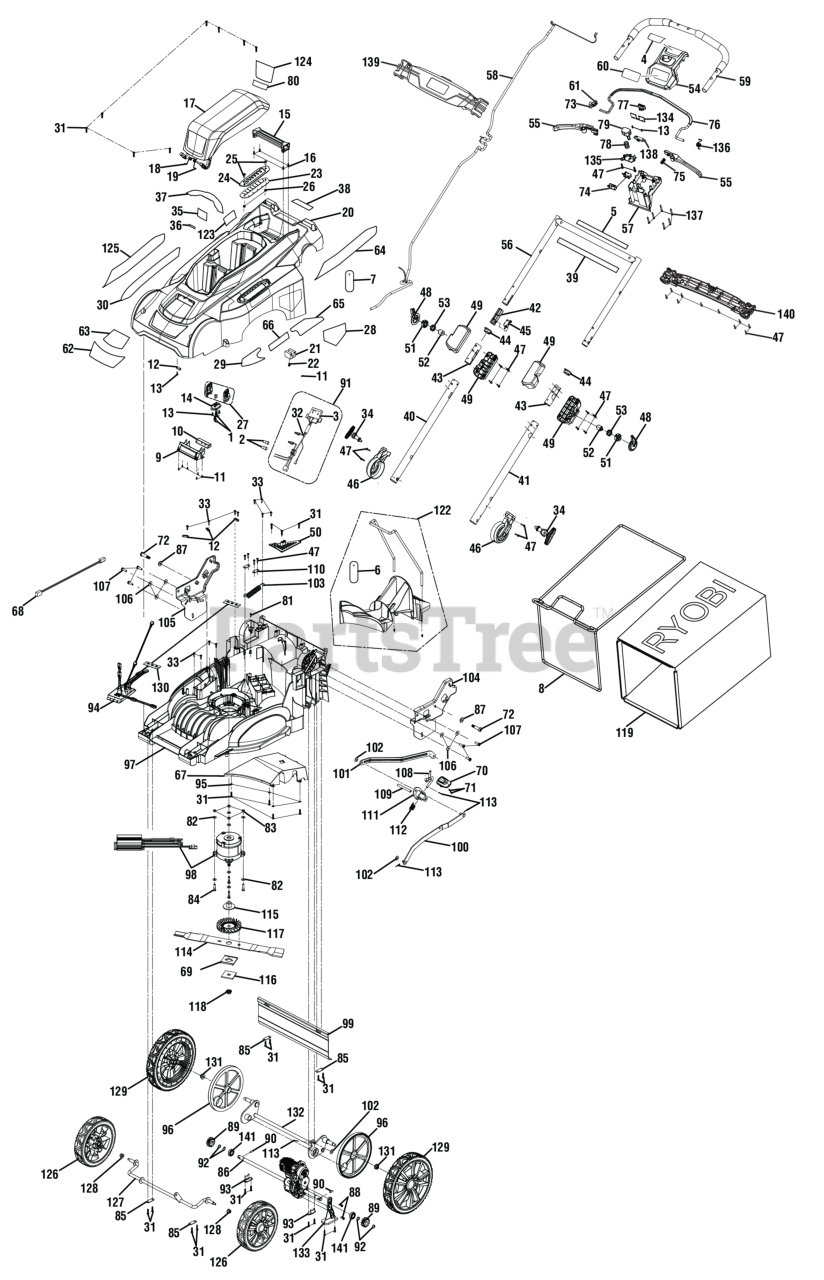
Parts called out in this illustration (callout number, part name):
1	Female Terminal
2	Close-End Connector
3	Battery Hold Assembly
4	Starting Instructions Label
5	Handles Fully Extended Label
6	Mulch Plug Hangtag
7	Start Key Hangtag
8	FRAME, 20 INCH GRASS BAG, BLACK
9	LED Cover
10	Light Reflector
11	Screw (M3 x 8 mm, Pan Hd., Pan Hd)
12	Wire Press Plate
13	Screw (M4.2 x 12 mm, T20 Torx Pan Hd.)
14	Key Holder
15	Carry Handle
16	Screw (M4 x 10 mm, T20 Torx Pan Hd.)
17	Battery Cover (Inc. Key Nos. 80 & 124)
18	Battery Door Right Torsion Spring
19	Battery Door Left Torsion Spring
20	TOP COVER W/ LABELS
21	SENSOR SWITCH FOR GRASS BAG
22	Screw w/Washer (M4 x 10 mm, T20 Torx Button Hd.)
23	Shifter Boot
24	Height Adjustment Plate
25	SCREW (M5 x 16 mm SOC. WASHER HD. CAP)
26	Lock Nut (M5 x 0.8 mm)
27	START KEY W/ HANG TAG
28	Danger Label (No Hands/Feet)
29	Front Green Accent Label
30	Side Green Accent Label
31	Screw (M4 x 20 mm, T20 Torx Pan Hd. S.T.)
32	Inner Wire with Terminal
33	Screw (M4 x 16 mm, T20 Torx Pan Hd.).
34	SPRING PIN ADJUSTMENT ASSEMBLY
35	Wet Conditions Warning Label
36	Onboard Battery Storage Label
37	Start Key Warning Label
38	Attachment User Callout Label
39	Handle Logo Label
40	STEEL TUBE,LOW RIGHT HANDLE TUBE
41	STEEL TUBE,LOW LEFT HANDLE TUBE
42	Switch Plug Housing
43	Handle Tube Bushing
44	Handle Tube Bushing (Small)
46	HINGE SHROUD
47	Screw (M4 x 18 mm, T20 Torx Pan Hd.)
48	Side Handle Latch
49	Handle Latch Assembly
50	PLASTIC,COVER FOR TRANSMISSION ASSY\ ABS
51	Disc Holder
52	Side Compression Disc
53	Handle Compression Spring
54	UPPER HANDLE SUPPORT ASSEMBLY W/ LABEL
55	TRIGGER ASSEMBLY
56	UPPER HANDLE TUBE W/ LABEL
57	UPPER HANDLE SUPPORT ASSEMBLY
58	CORD, 5PCS INNER WIRE AND PLUG ASSY
59	Upper Handle Assembly
60	Handles Fully Extended Label
61	Actuator Switch
62	LABEL, FRONT ""BRUSHLESS""
63	Ryobi 40V Lithium Label
64	Brushless Label (Left)
65	Single Point Height Adjustment Label
66	Cut Height Label
68	Inner Wire with Connector Between Transmission & PCBA
71	Screw (M3 x 9 mm, Flat Hd.)
72	Screw (M8 x 33 mm, Hex Hd.)
73	Stop Switch (Momentary Contact)
74	On/Off Switch
75	Compression Spring
76	Bail Handle (Power Lever)
77	Thumb Pad
78	Safety Button Spring
79	Safety Button
80	Main Warning Label (Part 1)
81	Screw (M3 x 12 mm)
82	Washer (ID6.2 x OD15 x 0.08t)
83	Lock Nut (M6)
84	Bolt (M6 x 26 mm, Hex Hd.)
85	Axle Pressure Plate
86	Transmission Assembly
87	Washer (ID8.5 x OD20.5 x 2 mm x 2t)
88	Screw (T20 x 12 mm)
89	Drive Gear
90	Gear Shaft
91	BATTERY HOLDER AND WIRE ASSEMBLY
92	Retaining Ring
93	Mounting Plate
94	DRIVE MOTOR CONTROLLER
95	Washer (ID4.5 x OD10 x 1t)
96	Wheel Cover
98	MOTOR 10035#, CONTROLLER ASSEMBLE,HUAJIE
99	Rear Protective Guard
100	Forward Linkage
101	Rear Lift Rod
102	Washer (ID8.4 x OD18 x 1t)
103	Rentention Spring
104	STAMPING, LEFT HANDLE BRACKET
105	STAMPING, RIGHT HANDLE BRACKET
106	Washer (1/4 in., Type A)
107	Screw (1/4-15 x 3/4 in., T30 Torx Pan Hd.)
108	Lever Arm
109	Axle (Height Adjustment)
110	Pressure Plate (Height Adjustment)
111	Height Adjustment Bracket
112	Torsion Spring (Height Adjustment)
113	Cotter PinÏ? (2.5)
114	Bagging Blade
115	Motor Shaft Bushing
116	Metal Blade Retainer
117	Motor Fan Blade Adapter
118	Blade Nut (M10 x 1.25, Hex Flange Hd.)
119	GRASS BAG
122	Mulch Plug Assembly (Inc. Key No. 6)
123	LABEL, DATA, RY401120
124	Main Warning Label (Part 2)
125	Brushless Label (Right)
126	PLASTIC,8'' WHEEL ASSEMBLY
127	Front Axle
128	Flange Lock Nut (M8 x 1.25 mm)
129	PLASTIC, 10"" WHEEL ASSEMBLY
131	Lock Nut (3/8-16, Flange)
132	Rear Wheel Axle w/Rotation Plate
133	Transmission Holder
134	Dust Shield
135	Spring Holder
136	Torsion Spring
137	Screw (M4-18 x 30 mm, T15 Torx Soc. Hd.)
138	Variable Switch
139	Front Upper Handle Support
140	Rear Upper Handle Support
141	Ball Bearing (OD28.6 x ID12.7 x 8)
